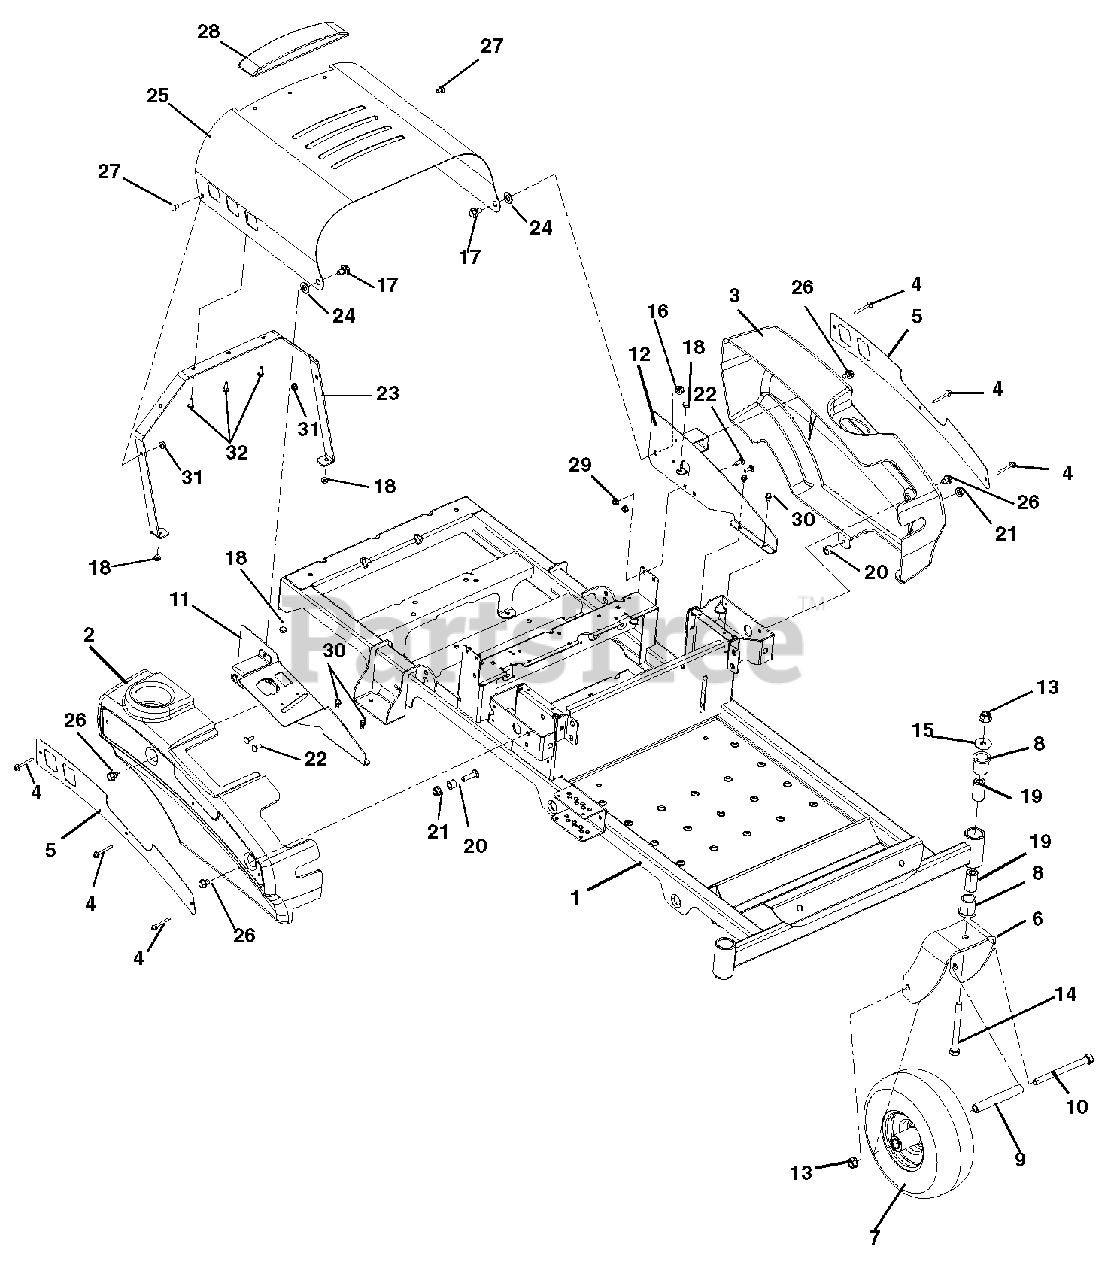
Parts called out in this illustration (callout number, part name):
1	Weldment, Frame
2	Fender, Right Hand
3	Fender, Left Hand
4	Rivet, Nylon
5	Plate, Fender
6	Fork, Caster
7	Wheel/Tire Assembly, 11.0 x 4.0 x 5.0
8	Bushing, Flange 1.00 x 1.25 x 1.50 x 1.50
9	Spacer, Wheel
10	Bolt, Hex .50-13 x 6.50 Grade 5
11	Weldment, Fender Mount Right Hand
12	Weldment, Fender Mount Left Hand
13	Nut, Locking-Top-Flange .50-13
14	Bolt, Hex .50-13 x 5.00 Grade 5
15	Washer, Flat Steel .511 x 1.441 x .125
16	Nut, Locking-Top-Flange .38-16
17	Bolt, Shoulder .375-16 x .135
18	Bumper Grommet .125 x .250 Diameter
19	Spacer, Caster
20	Bushing, Sleeve .391 x .688 x .52
21	Nut, .38-16 Nyloc Flange
22	Bolt, Round Head Square Neck .25-20 x .75 Grade 5
23	Hood Brace
24	Washer, Flat-Nylon .52 x 1.00 x .08
25	Hood
26	Screw, Tapping .38-16 x .50
27	Bolt, Round Head Square Neck .25-20 x .50 Grade 5
28	Trim, Hood
29	Nut, .25-20 Nyloc Flange
30	Screw, Tapping .25-20 x .50 Hex Washer Head Thread
31	Nut, Locking Top Flange .25-20
32	Screw, Phillips Pan Head 12-11X5/8
